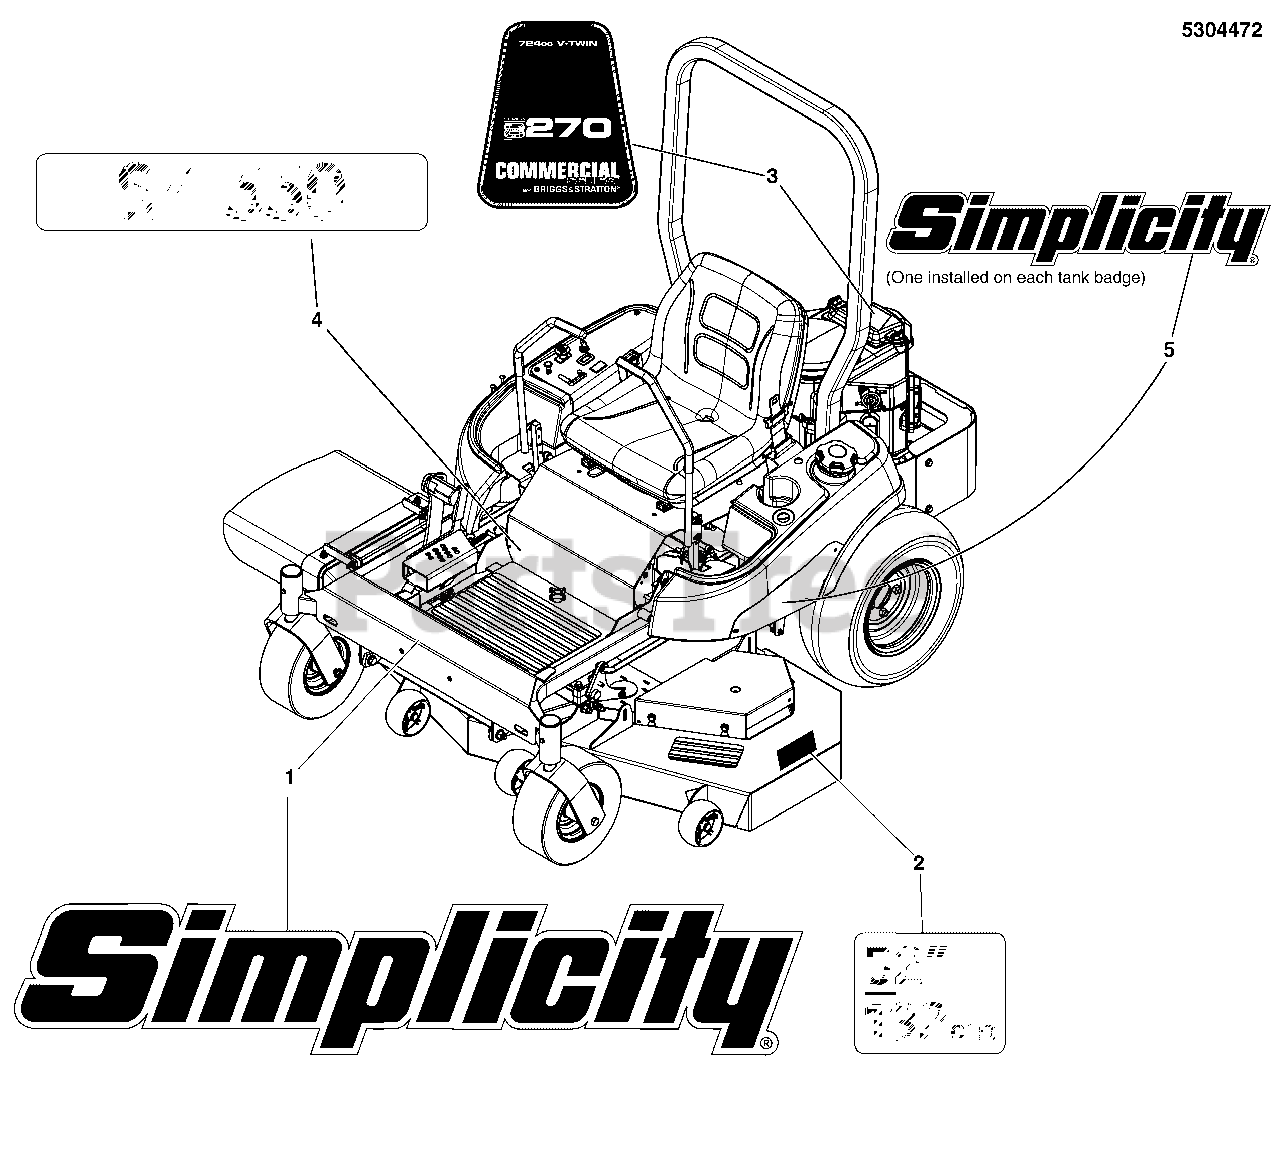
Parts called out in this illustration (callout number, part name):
1	DECAL, SMI LOGO 10.47"
2	DECAL, MOWER WIDTH 52IN/132CM
3	LABEL, POWER
4	DECAL, SMI, SZT550
5	DECAL, LOGO SIMPLICITY SILVER
